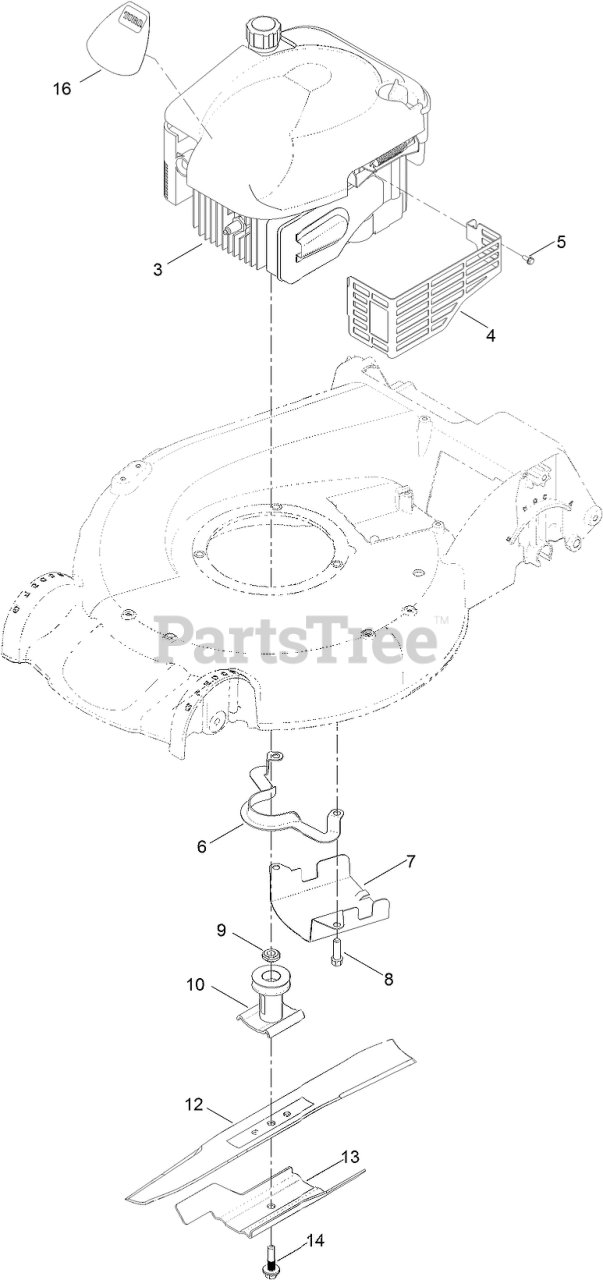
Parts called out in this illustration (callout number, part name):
4	SHIELD-MUFFLER
5	SCREW-TAPTITE
6	GUIDE-BELT
7	SHIELD-GRASS
8	SCREW-TAPTITE
9	Spacer-Driver
10	DRIVER-BLADE
12	BLADE-RECYCLING
13	Accelerator-Blade
14	BOLT-BLADE
16	DECAL-SHROUD
